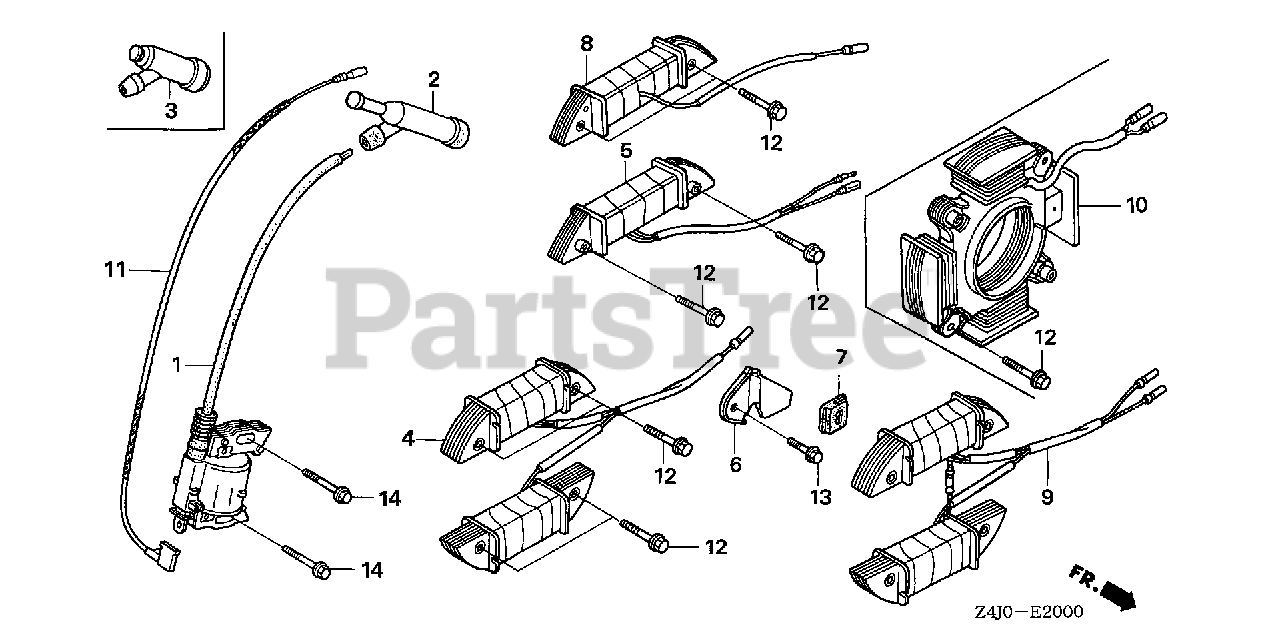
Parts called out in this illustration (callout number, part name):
1	COIL ASSY., IGNITION Use up to Engine SN 1530314.
2	CAP ASSY., NOISE SUPPRESSOR (Honda Code 3526837). (NICHIWA Y-EZ RTFM256)
11	WIRE, STOP SWITCH (370MM)
14	BOLT, FLANGE (6X25) Use up to Engine SN 2056819.
